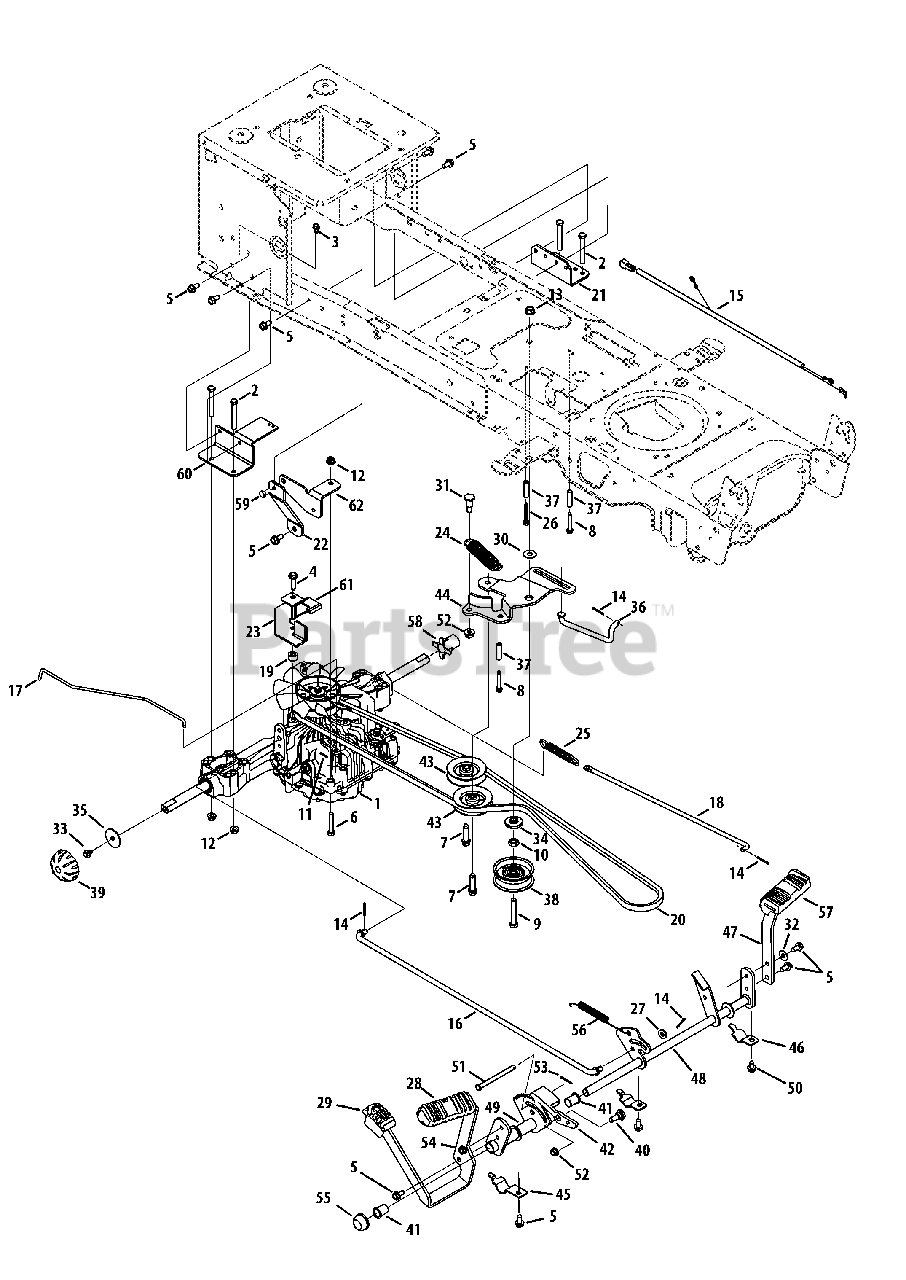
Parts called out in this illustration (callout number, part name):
1	Transmission, Tuff Torq K46
2	Hex Screw, 5/16-18, 2.50, Gr5, Std
3	Screw, Self-tapping, 1/4-20, 0.500
4	Screw, Self-tapping, 5/16-18, 1.250
5	Screw, Self-tapping, 5/16-18, .750
6	Hex Screw, 5/16-18, 1.75, Gr5
7	Screw, Self-tapping, 3/8-16, 1.500
8	Screw, Self-tapping, 1/4-20, 1.625
9	Hex Screw, 3/8-16, 2.25, Gr5
10	Nut, Jam, 7/16-20, Gr2
11	Pin, Cotter, 3/32, 1.0
12	Nut, Flange Lock, 5/16-18, Nylon
13	Nut, Flange Lock, 3/8-16
14	Pin, Cotter, 3/32, 1.0
15	Jumper Harness, Ground & Reverse
16	Rod, Control, Tuff-Torq
17	Rod, Hydro Bypass
18	Rod, Brake, Tuff-Torq
19	Spacer, .330 x .715 x .430
20	Belt, V-Type
21	Bracket, Mount, Tuff-Torq
22	Bracket, Tuff Torq
23	Bracket, Belt Keeper
24	Spring, Extension, 1.00 Dia x 4.75
25	Spring, Extension, .59 Od x 4.00
26	Screw, Self-tapping, 1/4-20 x 1.75
27	Washer, Flat, .375 x .738 x .063
28	Pad, Pedal, Forward
29	Pad, Pedal, Reverse
30	Wash, Flat, .385 x 1.00 x .030
31	Scr, Shldr, .50 x .685 3/8-16
32	Washer, Bell, .340 x .872 x .060
33	Screw, 5/16-24 x .750
34	Spacer, Shoulder, 1.375 x .380 x .183
35	Washer, Flat, .350 x 1.59 x .062
36	Rod, Transmission, Bypass
37	Spacer, .260 x .372 x 1.420
38	Pulley, Idler, Flat 2.75 OD
39	Cap, Hub
40	Bolt, Shoulder, .500 x .270, 3/8-16
41	Bearing, Flange, .630 x .695 x .60
42	Latch, Cruise
43	Pulley, Idler, V-Type x 3.06
44	Bracket, Idler, Center Double
45	Bracket, Support, Pedal Strap
46	Bracket, Support, Pedal Strap 5/8
47	Bracket, Pedal, Brake
48	Control Assembly, Brake
49	Bracket Assembly, Pedal, Hydro
50	Screw, Self-tapping, 5/16-18, 0.625,
51	Pin, Clevis, 5/16 x 3.985
52	Nut, Flange Lock, 3/8-16, Nylon
53	Pin, Cotter, Bow-Tie 72
54	Bracket, Pedal, Hydro
55	Cap, Push 5/8
56	Spring, Extension, .63 Dia x 4.95
57	Pad, Pedal, Brake
58	Sleeve, .765 Id x 1.500
59	Hex Cap Screw, 3/8-16 x .75
60	Bracket, Mount
61	Bracket, Belt
62	Bracket, Support
